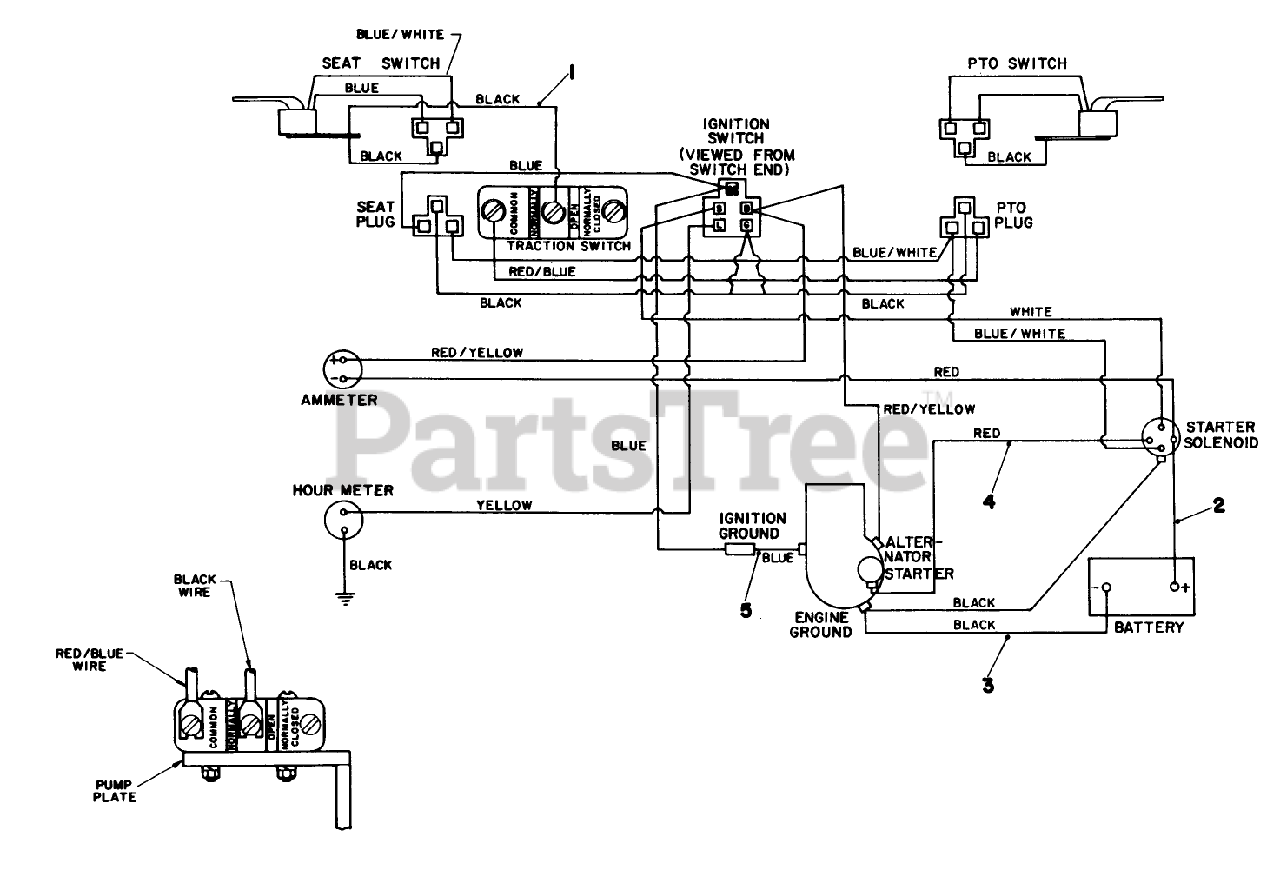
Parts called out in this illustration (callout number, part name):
1	WIRE HARNESS
2	BATT/SOLENOID WIRE
3	BATTERY GROUND WIRE
4	SOLENOID TO START WIR
5	ENGINE GROUND WIRE
